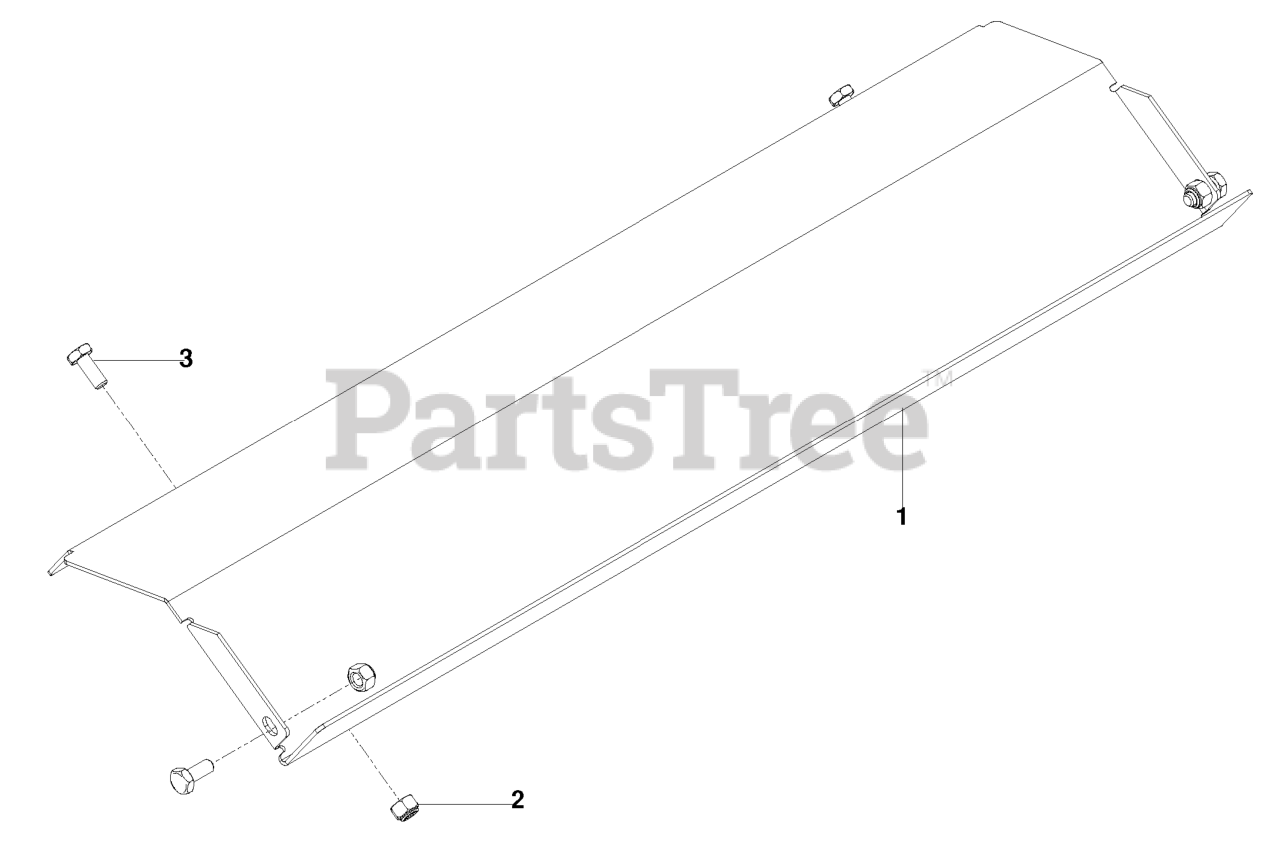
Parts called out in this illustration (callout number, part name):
1	REAR COVER ORANGE
2	NUT.1/4-20.HEX.NYLOC.ZD
3	HCS 1/4C X 5/8
